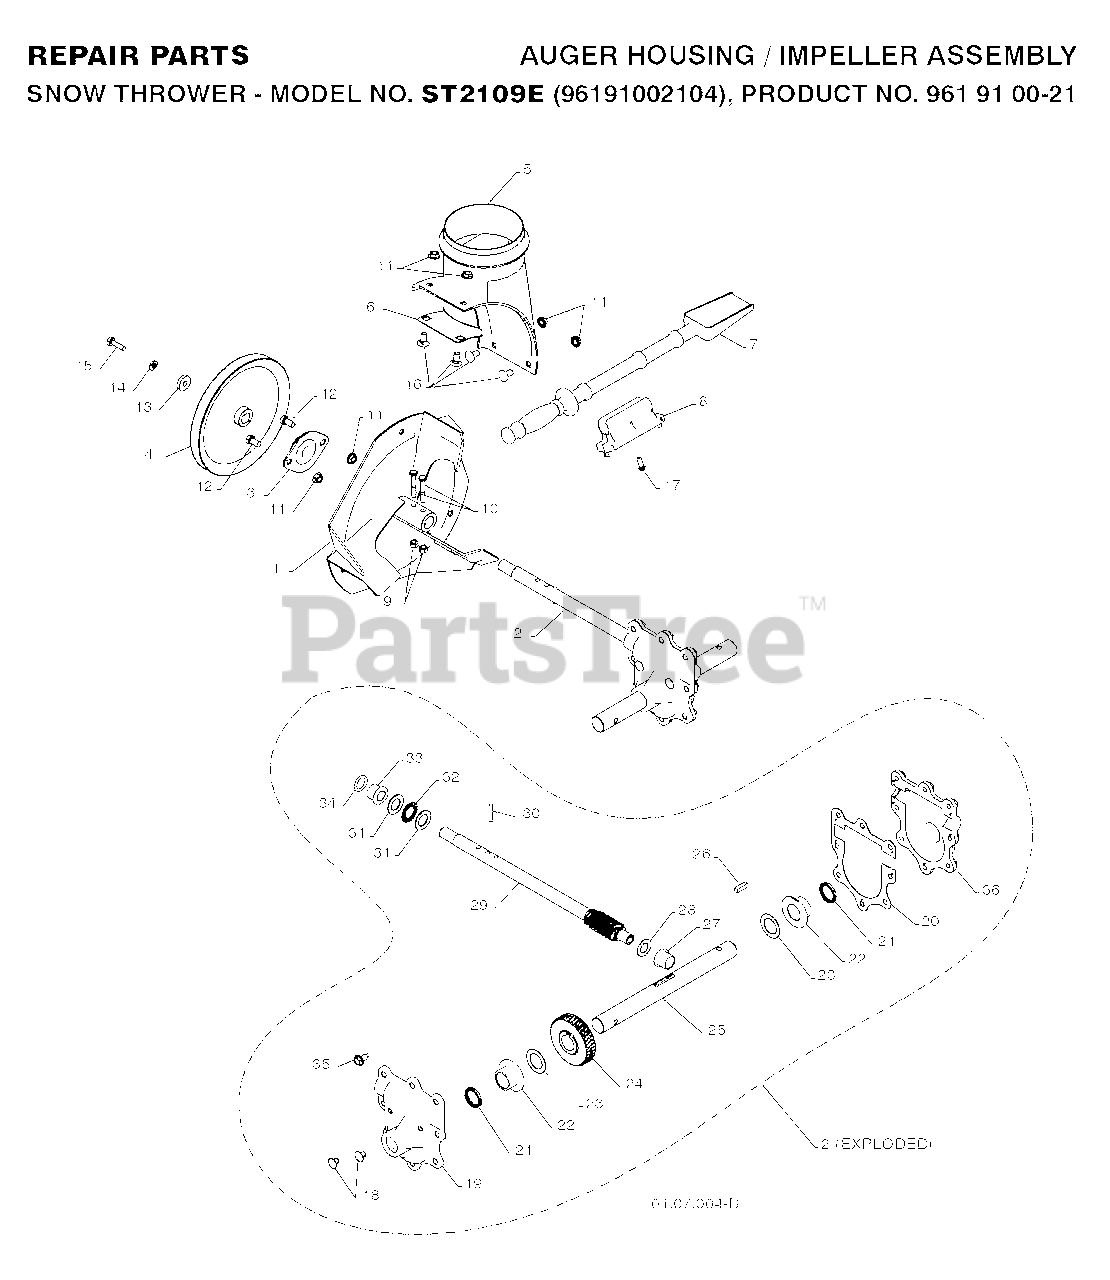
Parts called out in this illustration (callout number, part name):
1	IMPELLER ASSY
2	GEARBOX.ASSEMBLY.AUGER
3	BEARING FLANGE
4	PULLEY, IMPELLER
5	BASE DISCHARGE CHUTE
6	BRACKET, CORNER DISCHARGE
7	CLEAN OUT TOOL
8	CLIP.CLEANOUT.TOOL
9	LOCKNUT
10	SCREW.HEX.HD1/4-20X
11	NUT.FLANGE.5/16
12	BOLT, HEX HEAD 5/16-18
13	WASHER, FLAT
14	LOCKWASHER
15	CAPSCREW.HX.HD.5/16-18X1.00.NY
16	BOLT.CARRIAGE.5/16-18X
17	SCREW.HWH.13-16-5.8.BZP
18	CASE PLUG
19	GEARBOX HOUSING-RH
20	GEARBOX GASKET
21	OIL SEAL
22	FLANGE BUSHING-1"
23	WASHER TRUST 1"
24	WORM GEAR
25	AUGER SHAFT
26	KEY, SQUARE 1/4 X .875
27	FLANGE BUSHING-5/8
28	WASHER, THRUST 5/8
29	SHAFT, IMPELLER
31	WASHER, THRUST 3/4
32	BEARING TRUST 3/4
33	BUSHING, FLANGE 3/4
35	HEX SCREW-5/16 X 3/4
36	GEARBOX HOUSING - LH
